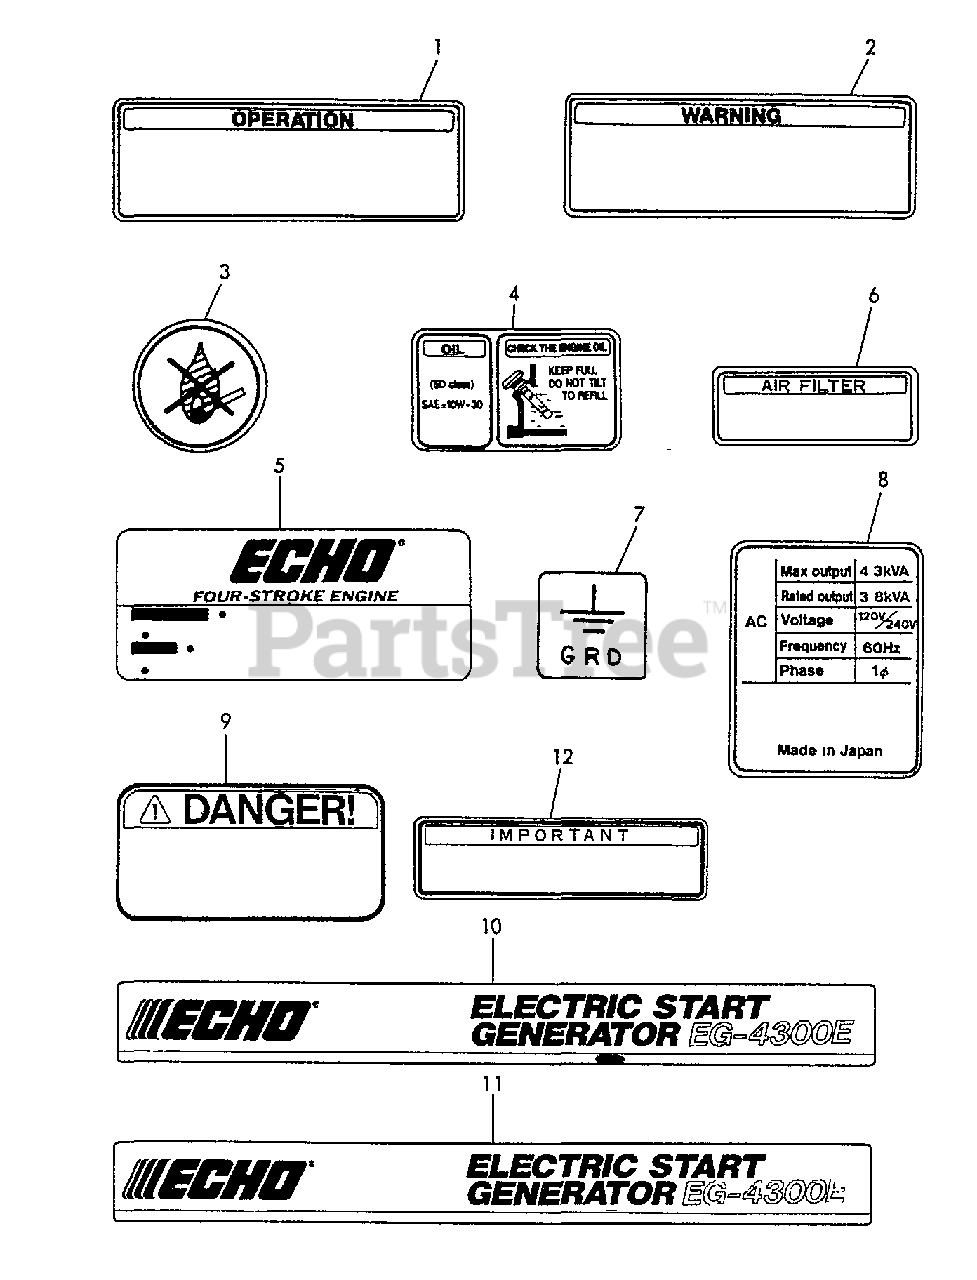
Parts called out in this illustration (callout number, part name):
1	LABEL - OPERATION
2	LABEL - WARNING
3	LABEL - NON FIRE
4	LABEL - OIL
5	LABEL - ECHO
6	LABEL - AIR CLEANER
7	LABEL - GROUND
8	LABEL - GENERATOR
9	LABEL - DANGER
10	LABEL - GENERATOR
11	LABEL - GENERATOR
12	LABEL - IMPORTANT
